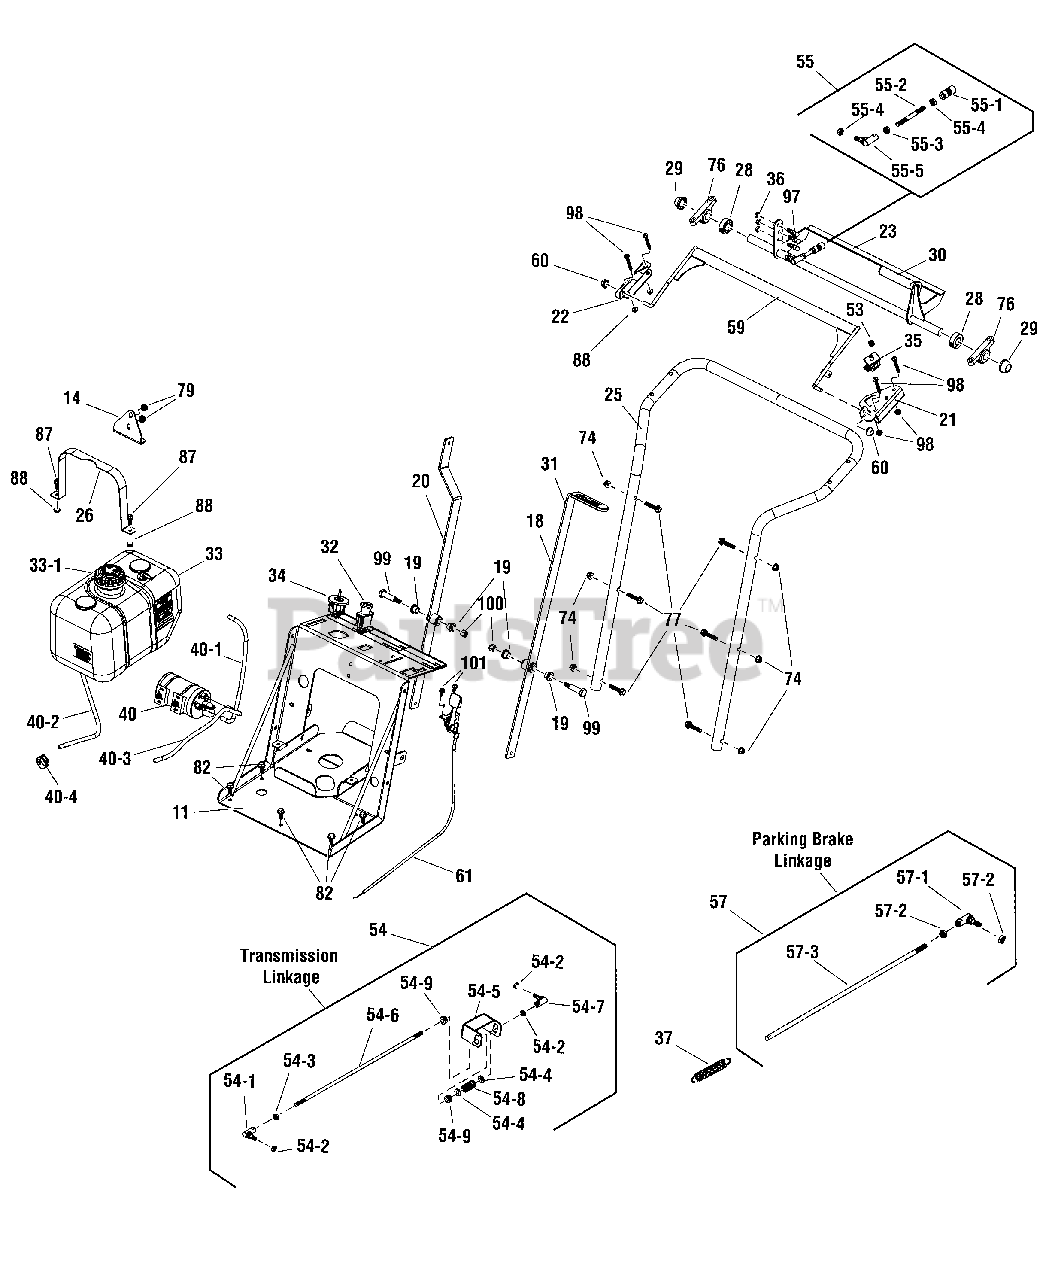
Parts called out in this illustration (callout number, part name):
11	DASH BOARD
14	FUEL TANK CLAMP
18	BRAKE HANDLE
19	OILITE BUSHING
20	SPEED CONTROL ARM
21	BRACKET, LH
22	BRACKET, RH
23	SPEED CONTROL HANDLE
25	HANDLE, OPERATOR WITH GRIPS
26	FUEL TANK HOLD-DOWN STRAP
28	SPLIT SHAFT COLLAR, 3/4"
29	PUSH CAP, 3/4"
30	GRIP, REVERSE LEVER
31	GRIP, PARKING BRAKE
32	PTO ENGAGEMENT SWITCH
33	FUEL TANK, 2.5 GAL
33-1	CAP, FUEL TANK
34	IGNITION SWITCH W/KEY
35	OPERATOR PRESENCE SWITCH
36	HEX NUT, 5/16"-24 RH
37	SPRING, PARKING BRAKE
40	EVAP CANISTER
40-1	VAPOR LINE, 1/4" ID
40-2	FUEL LINE, LOW-PERM, 1/4" ID
40-3	VAPOR LINE, 3/16" ID
40-4	SPRING ACTION HOSE CLAMP, 1/2"
53	RETURN SPRING, OPP. PRESENCE
54	TRANSMISSION LINKAGE
54-1	BALL JOINT, 5/16"-24 LH THREAD
54-2	HEX NUT, 5/16"-24 RH
54-3	NUT, 5/16"-24 LH
54-4	FLAT WASHER, 5/16"
54-5	GUIDE BRACKET, SPEED CONTROL
54-6	FORWARD/REVERSE ROD
54-7	BALL JOINT, 5/16"-24 RH THREAD
54-9	Split Shaft Collar, 5/16"
55	SPEED CONTROL LINKAGE
55-1	Ball Joint, Quick Link Socket, 5/16"-24 RH
55-2	SPEED CONTROL ROD, UPPER
55-3	NUT, 5/16"-24 LH
55-4	HEX NUT, 5/16"-24 RH
55-5	BALL JOINT, 5/16"-24 LH THREAD
57	PARKING BRAKE LINKAGE
57-1	BALL JOINT, 5/16"-24 RH THREAD
57-2	HEX NUT, 5/16"-24 RH
57-3	PARKING BRAKE ROD
59	OPERATOR PRESENCE BAR
60	PUSH CAP, 5/16" DIA.
61	THROTTLE CABLE
74	NUT, 5/16"-18 HEX FLANGED NYLOK
76	BEARING, SPEED CONTROL
77	5/16"-18 X 1-1/2" BOLT
79	5/16"-18 HEX NUT, SERRATED
82	BOLT, 5/16"-18 X 3/4"
87	1/4"-20 x 3/4" SERRATED HEX BOLT
88	1/4"-20 NUT
97	QUICK-LINK STUD, 5/16"-24 RH
98	SCREW, 1/4"-20 x 2"
99	BOLT, 1/2" x 1-1/2"
100	NUT, LOCK, 3/8"-16
101	BOLT, 1/4"-10 X 1/2" SERRATED HEX HEAD
